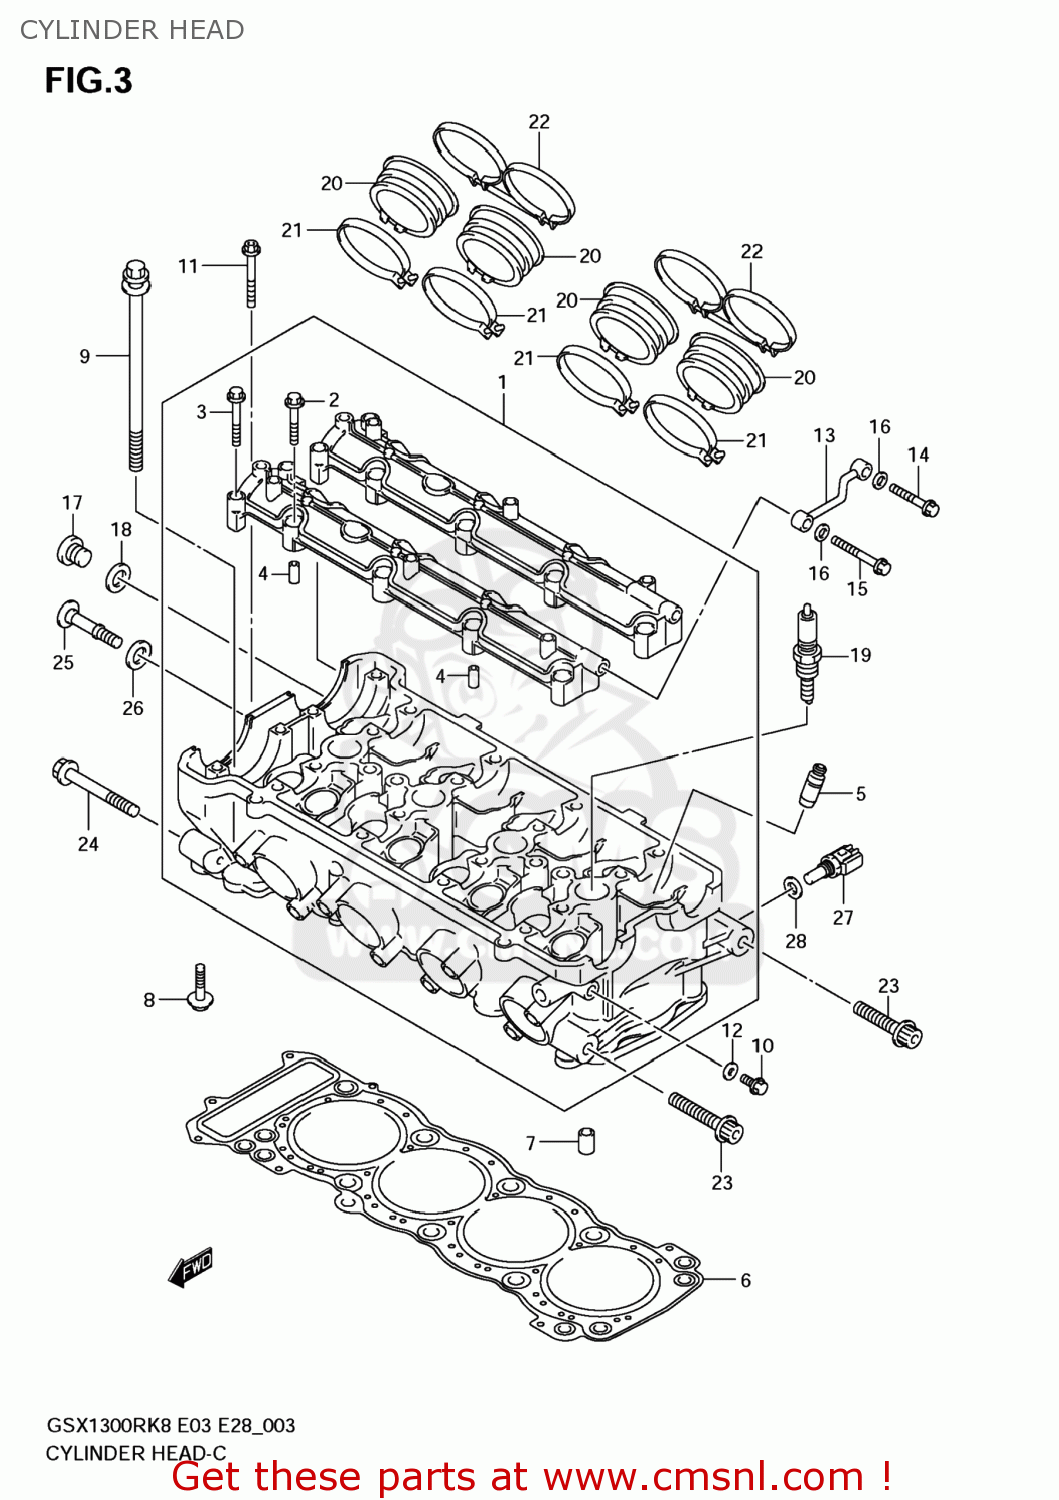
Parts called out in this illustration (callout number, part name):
1	HEAD ASSY,CYLINDER
2	BOLT(6X39)
3	BOLT(6X45)
4	PIN(6.2X8X16)
5	GUIDE,VALVE(OS:0.3)
6	GASKET,CYLINDER HEAD (NAS)
7	PIN
8	BOLT
9	BOLT,CYLINDER HEAD(L:180)
10	BOLT(6X12)
11	BOLT
12	GASKET(5.8X13X1.2) (NAS)
13	PIPE,CYLINDER HEAD OIL
14	BOLT
15	BOLT
16	WASHER
17	PLUG,16X8
18	GASKET(16X22X0.8) (NAS)
19	PLUG,SPARK(IU27D)
20	PIPE,INTAKE
21	CLAMP
22	CLAMP,INTAKE PIPE
23	BOLT(10X45)
24	BOLT(10X60)
25	BOLT,CYL HEAD SIDE FACE
26	WASHER,HEAD COVER
27	SENSOR,TEMP
28	GASKET(12X17X1) (NAS)
